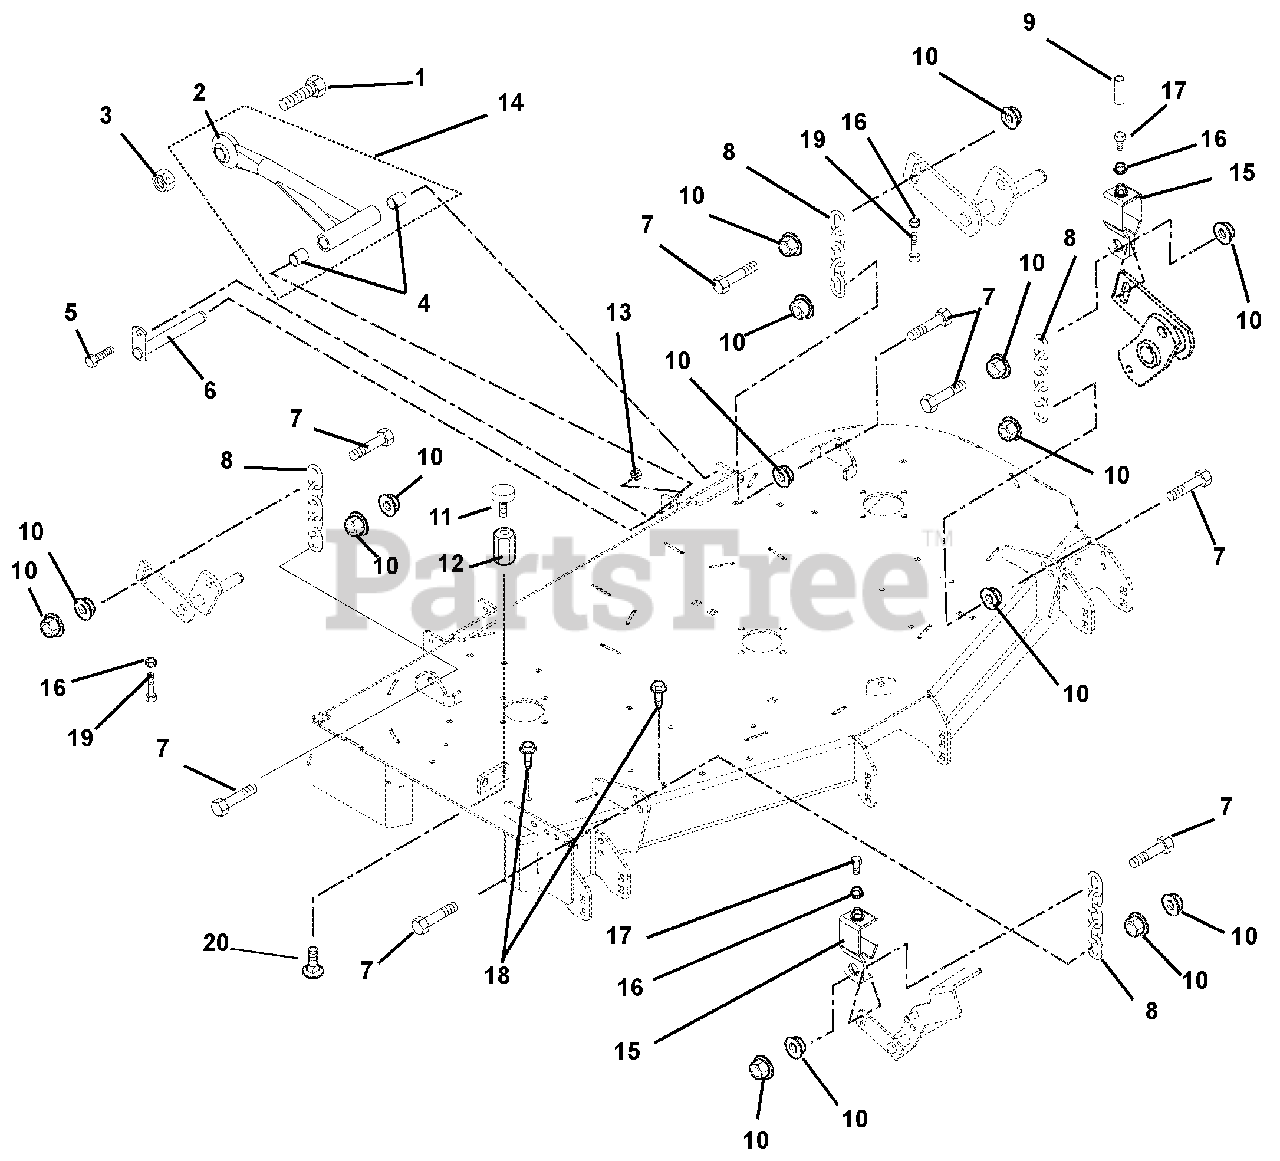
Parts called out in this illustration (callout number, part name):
1	BLT-HEX .875-9X2.75 GR5 YWZC
2	MOWER MOUNTING ARM WMT - BLACK
3	NUT-LK-CTR .875-9 YWZC
4	BRG, .750 X .875 X 1.000
5	@BLT-HEX .38-16X1.00 GR5 YWZC
6	WELDMENT, MOWER MTG. PIN
7	BLT, HEX M12-1.75X50 CLS8.8 YZ
8	CHAIN, LINK
9	CAP-VINYL .50ID X 1.50LG X.055
10	NUT-SPNLK-FLG M12-1.75 YZ
11	BUMPER, RUBBER
12	NUT, COUPLING .31-18 X 3.00
13	@NUT-LK-NYL-FLG .38-16 YWZC
14	ASSM, MOWER MOUNTING ARM
15	BRKT, DECK LEVELING
16	NUT- JAM .312-18 YWZC
17	BLT-HEX .312-18X2.00 FTH GR5YZ
18	@SCR-TAP .38-16X.50 HWH TR YWZ
19	BLT-HEX .312-18X1.50 FTH GR5YZ
20	BLT,RDHDSQNK .31-18X.75 LOCTIT
